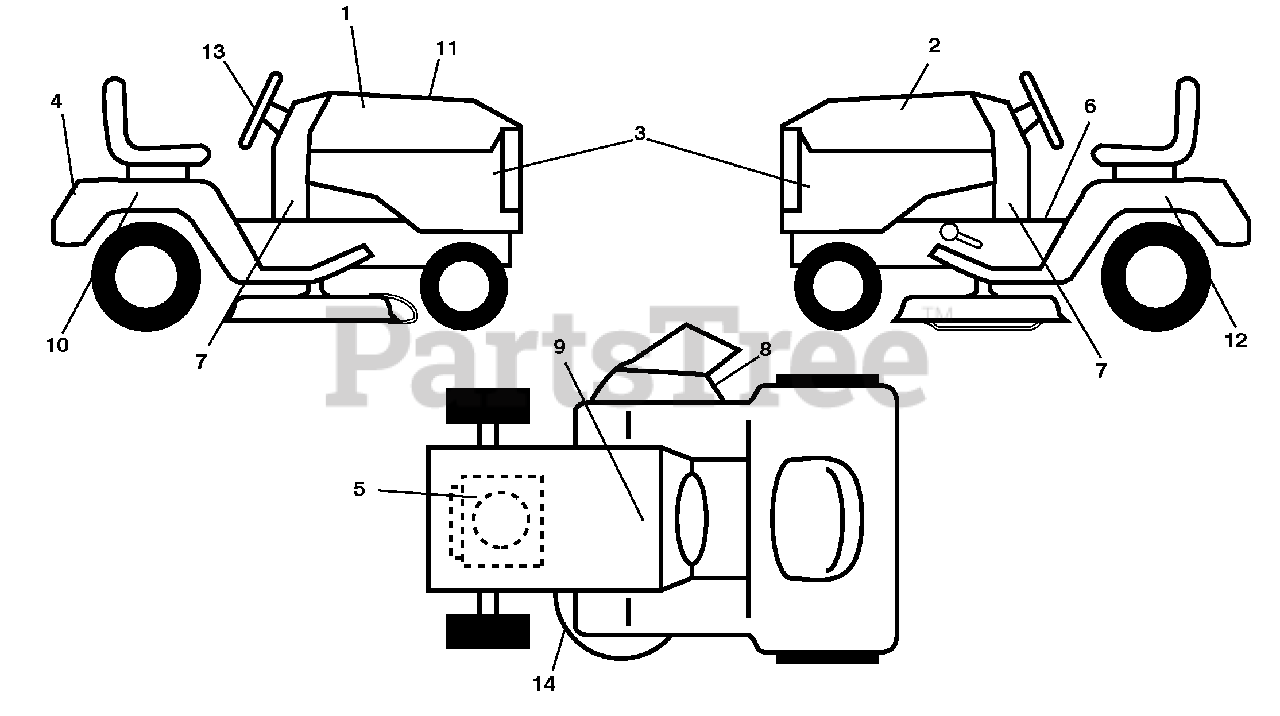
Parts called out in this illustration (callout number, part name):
1	Decal, Hood RH
2	Decal, Hood LH
3	Decal, Side Panel
4	Decal, Fender
5	Decal, Eng H.P.
6	Decal, Fender Operator's
7	Decal, Lower Dash
8	Decal, Warning
9	Decal, Battery Dnge/Poi
10	Decal, Fender SD RH
11	Decal, Replacement
12	Decal, Fender SD LH
13	Decal, Steering Wheel
14	Decal, Mower Schematic
14	Pad, Footrest Control
14	Decal, Bypass
14	Pad, Footrest, LH
14	Manual, Operator's (Eng/French)
14	Manual, Parts (Eng/French)
